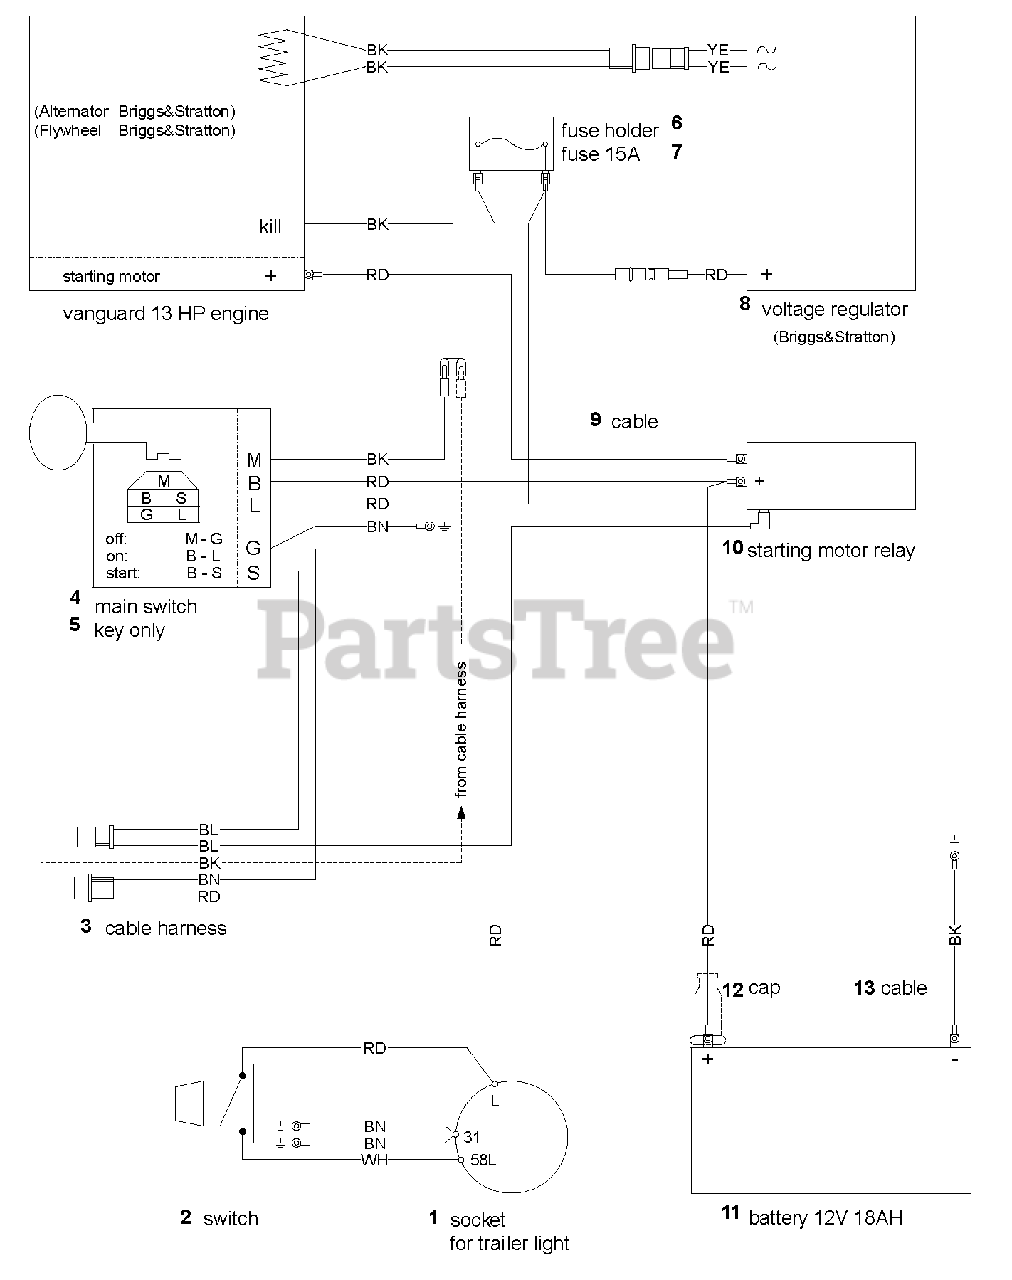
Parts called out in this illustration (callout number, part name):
1	Plug Socket, 12/7A
3	Harness, Wiring
4	Assembly, Starter Switch
5	Assembly, Key
6	Fuse Holder
7	15A, Fuse
8	Regulator
9	Cable Red
11	Battery, Rapid
13	Cable Black
